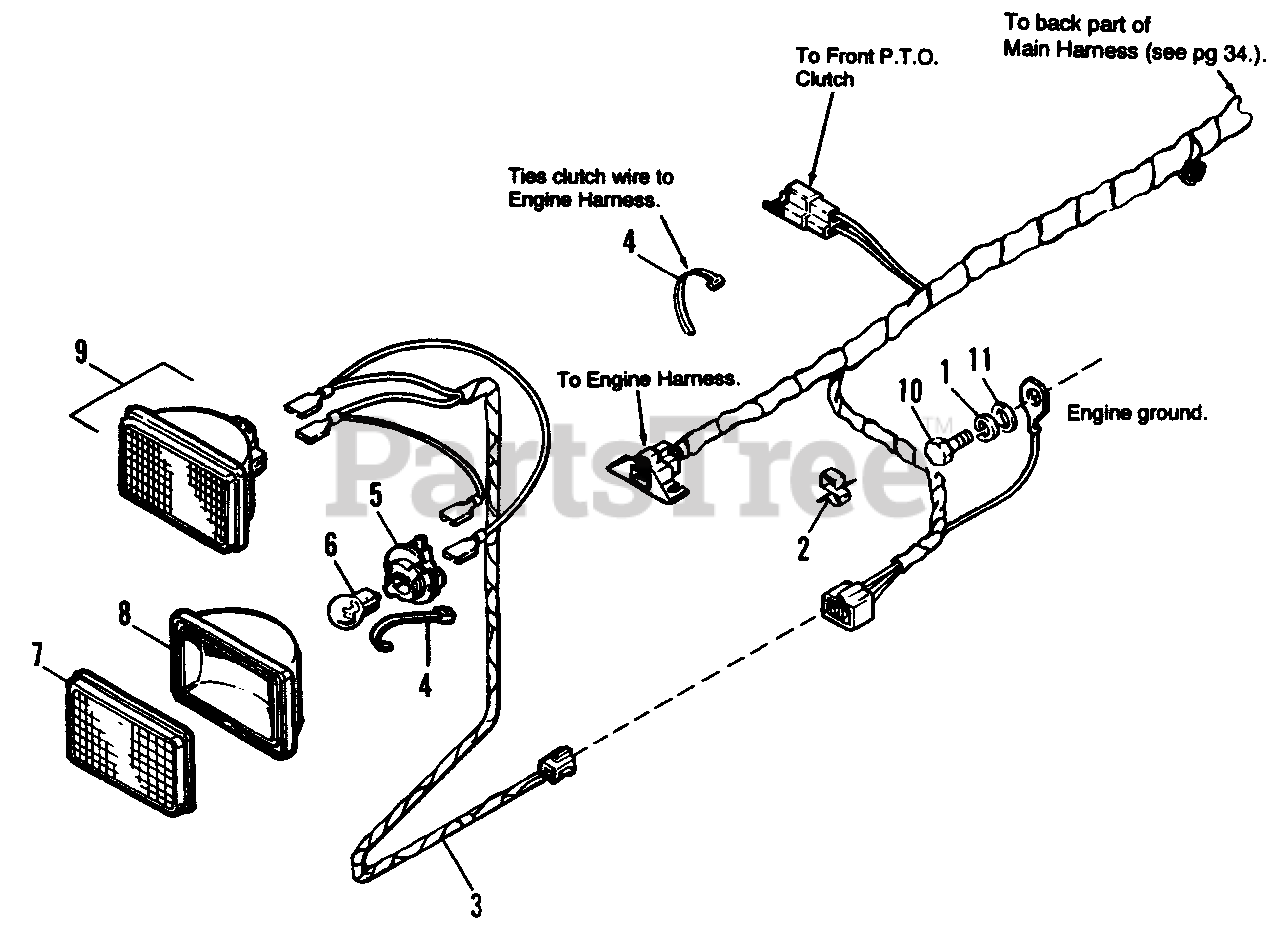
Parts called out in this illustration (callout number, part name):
1	LOCKWASHER, 7/16
3	HARNESS, Headlight
5	SOCKET, Bulb
6	BULB, 12.8V
7	LENS, Clear
9	HEADLIGHT ASSY. (Incl. Ref. No. 5, 6, 7 & 8)
10	SCREW, Hex Hd., 7/16-14 x 1
